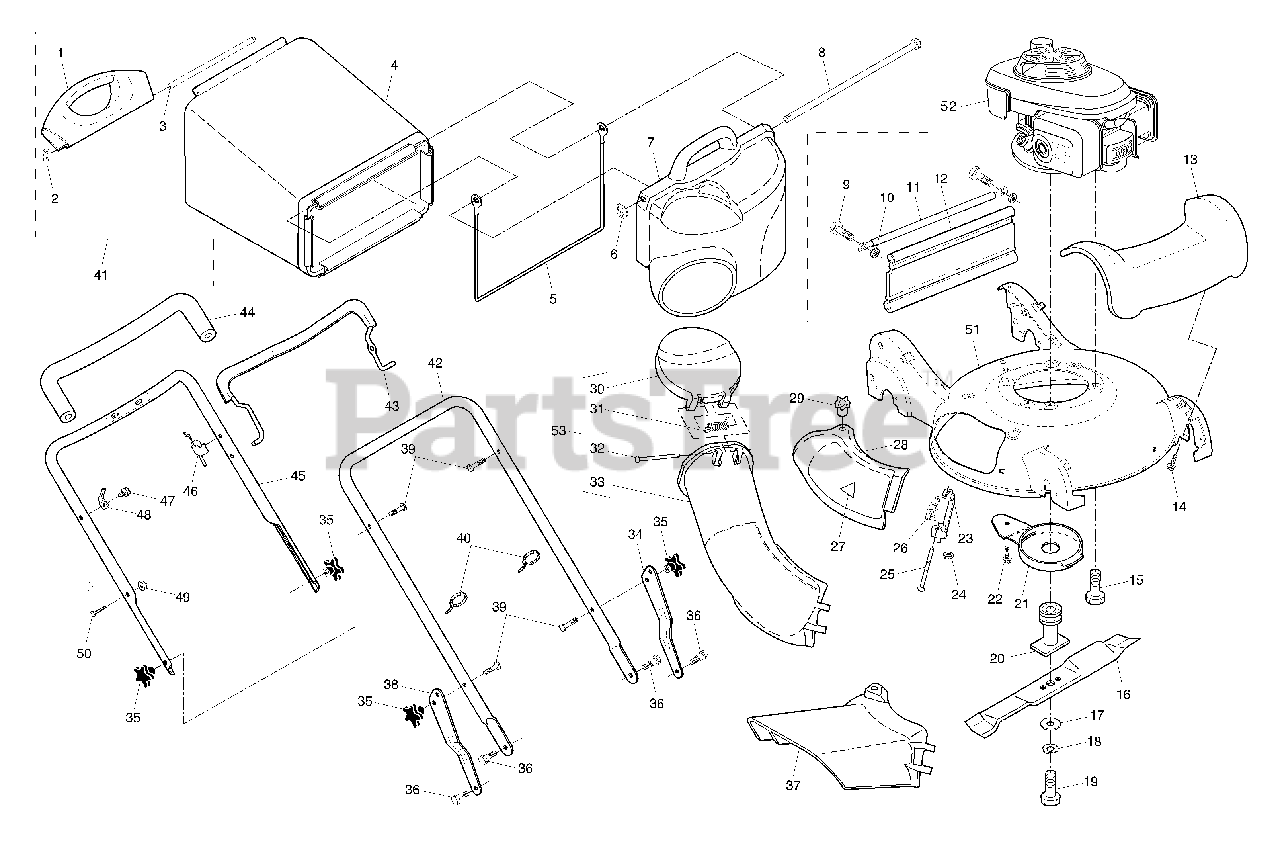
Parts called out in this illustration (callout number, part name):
1	Handle, Grassbag, Rear
2	Hairpin Cotter
3	Rod, Rear Handle, Grassbag
4	Grassbag
5	Frame, Grassbag
7	Door, Grassbag
8	Rod, Pivot
10	Nut, Hex
11	Tube, Rear Skirt
12	Skirt, Rear
13	Cover, Front
14	Screw, Hex Washer Head
15	Bolt, Engine Mounting
16	Blade, 21"
17	Washer, Hardened
18	Washer, Lock
19	Screw, Hex Head, Grade 8
20	Adapter, Blade
21	Debris Shield
22	Screw, Hex Head, Serrated
23	Mounting Bracket, Mulcher Door
24	Nut, Hex
25	Rod, Hinge
26	Spring, Mulcher Door
27	Decal, Danger
28	Mulcher Door
30	Door, Discharge Chute
31	Spring, Door, Discharge Chute
32	Rod, Door, Discharge Chute
33	Discharge Chute, Plastic
34	Adjustment Bracket, Lower Handle, LH
35	Knob, Star
36	Bolt, Shoulder
37	Deflector, Discharge
38	Adjustment Bracket, Lower Handle, RH
39	Bolt, Handle
40	Wire Tie
41	Grassbag Assembly, Complete
42	Handle Assembly, Lower
43	Bail, Control
44	Grip, Foam
45	Handle Assembly, Upper
46	Cable, Engine Zone Control
48	Bracket, Upstop
50	Rope Guide
51	Kit, Housing
53	Discharge Chute Assembly, Complete
